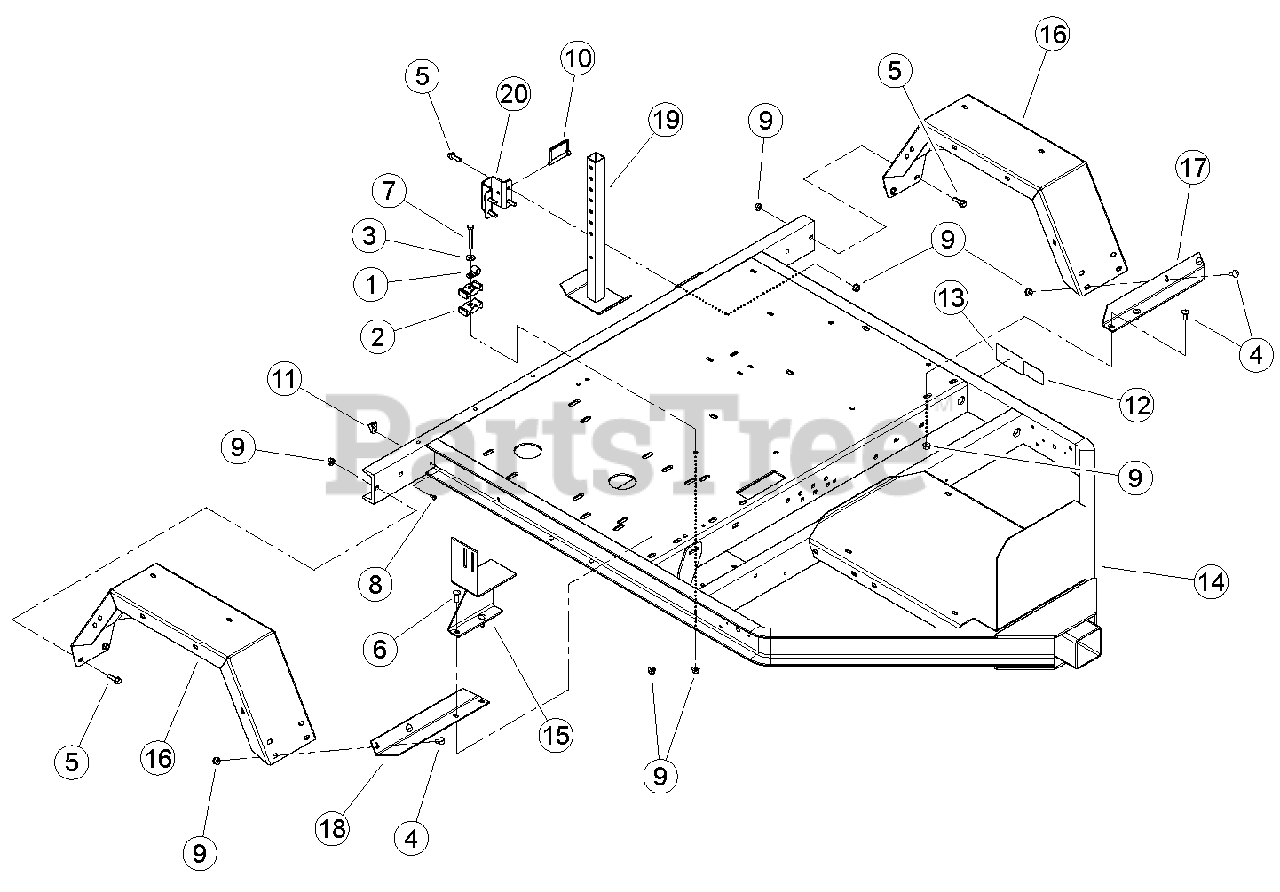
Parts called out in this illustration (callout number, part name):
1	CLAMP, 9/16 COATED
2	CLAMP, PLASTIC HOSE
3	WASHER, 3/8" FLAT ZP
4	BOLT, 3/8 X 1" GR5 CRG NC ZP
5	BOLT, 3/8 X 1-1/4 FLANGE NC
6	BOLT, 3/8 X 1-1/4" GR5 CRG NC ZP
7	BOLT, 3/8 X 2-3/4" GR5 NC HHCS ZP
8	RIVET, AL BLIND 1/4 X 3/4 DOME HEAD
9	NUT, 3/8-16 NYLOCK FLANGE
10	PIN, 3/8 X 2-3/4" SNAP
11	CLAMP, CABLE MOUNT
12	DECAL, P215/70R15 LOAD RATING
13	DECAL, EPA EMISSION
14	WELDMENT, CHIPPER TRAILER
15	WELDMENT, BELT GUIDE
16	FENDER, HEAVY DUTY
17	ANGLE, LH FENDER SUPPORT
18	ANGLE, RH FENDER SUPPORT
19	WELDMENT, REAR STABILIZER
20	GUIDE, TRAILER SUPPORT
